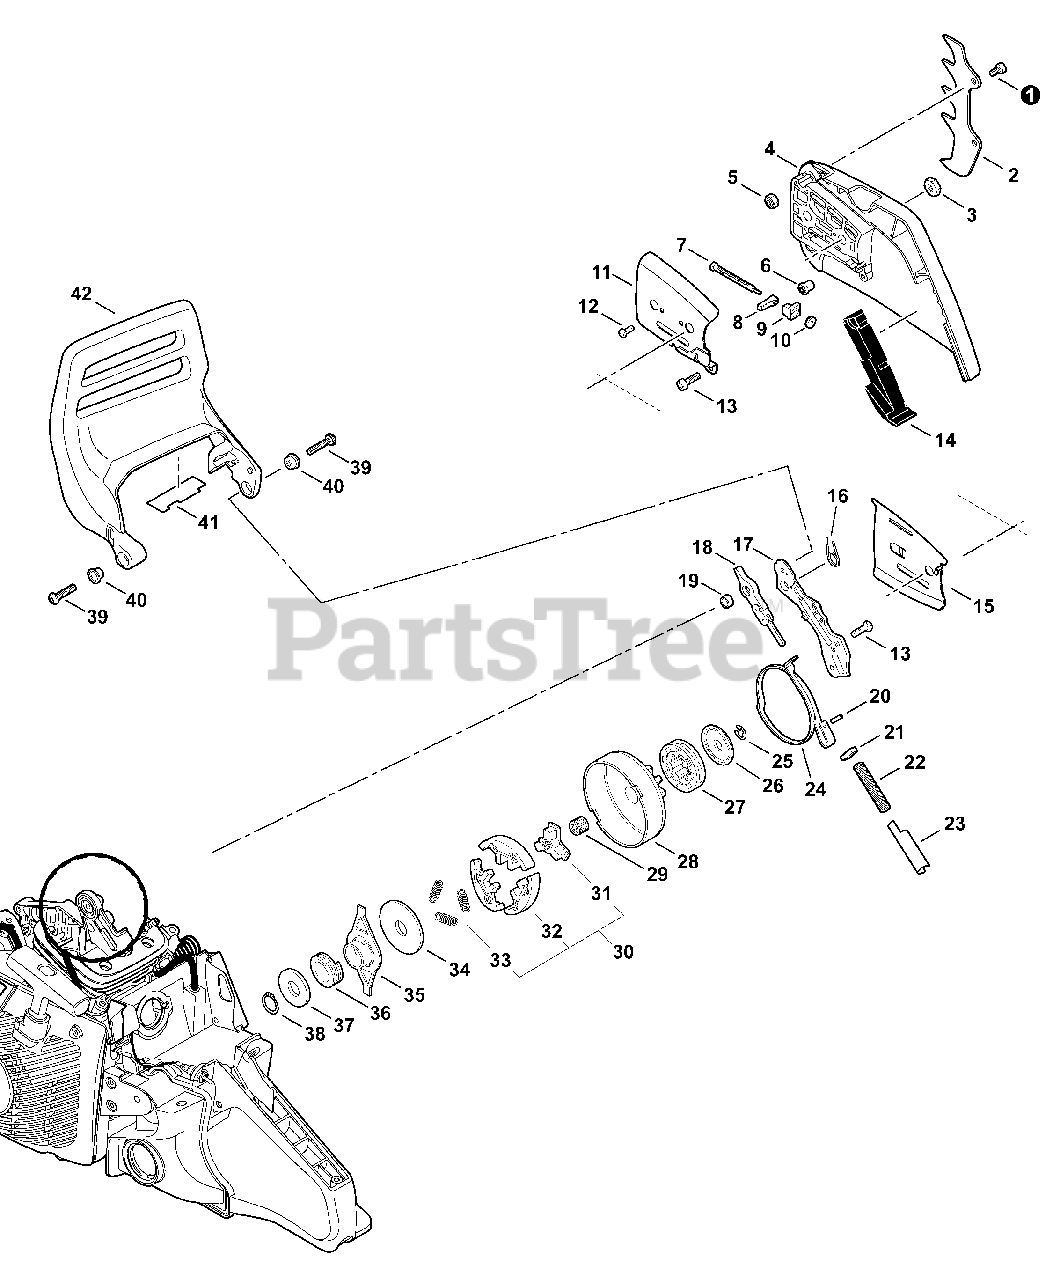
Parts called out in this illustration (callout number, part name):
1	BOLT, TORX 5×12
2	SPIKE, BUMPER
4	GUARD, SPROCKET
5	NUT, LOCK M5
6	GEAR, BEVEL
7	SCREW, CHAIN TENSION 63 MM
8	TENSIONER, CHAIN
9	GEAR, BEVEL
10	COLLAR 8
11	PLATE, GUIDE - OUTER
12	SCREW 3×5
13	BOLT, TORX 4×12
14	CUSHION
15	PLATE, GUIDE - INNER
16	SPRING, TORSION
17	COVER, BRAKE
18	CONNECTOR, BRAKE
19	SPACER 12×10×T: 1.0
20	PIN, SPRING 3x-9.8
22	SPRING, COMPRESSION Ø12×70.5
23	PLATE, SIDE
24	BAND, BRAKE
25	E-RING Ø8.1
26	WASHER 10
27	SPROCKET, RIM 3/8"×7T
28	DRUM, CLUTCH
29	BEARING, NEEDLE 10
30	CLUTCH ASSY
31	HUB, CLUTCH
32	SHOE SET, CLUTCH (3PCS)
33	SPRING, TENSION
34	PLATE, CLUTCH
35	COLLAR 15×19×73
36	GEAR, WORM
37	WASHER 15.5×22.5×0.5
38	RING, RETAINING 15
39	BOLT, TORX 5×16
40	COLLAR 11.2×16.2×T0.6
41	SHIELD, HEAT 75×27×0.15
42	LEVER, BRAKE
